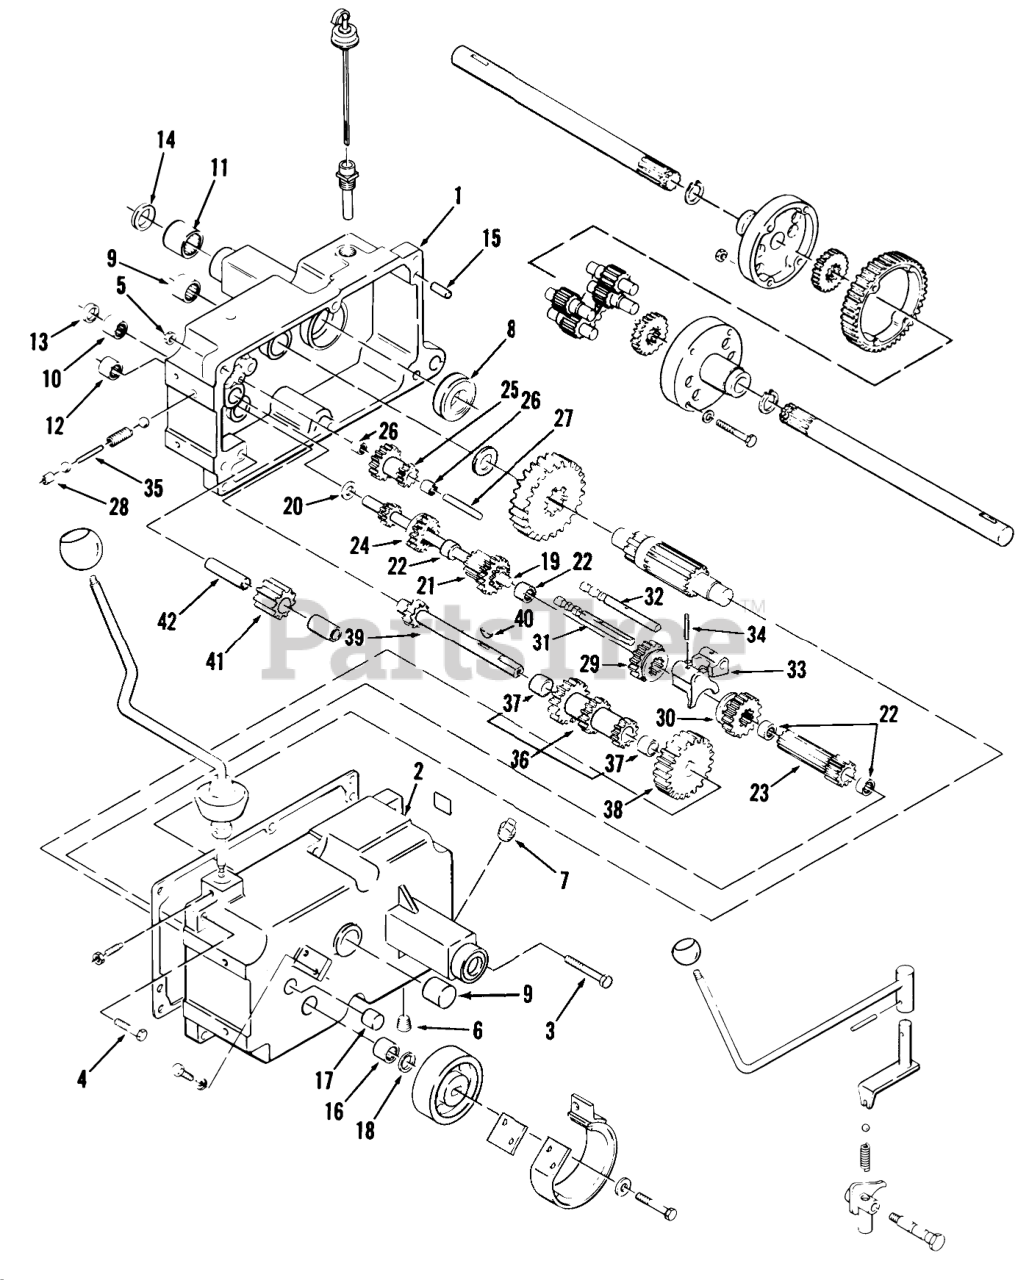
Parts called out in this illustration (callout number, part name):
1	CASE TRANS RH
1	Case-Trans RH 300-Series Only Note: this case half has recess in axle housing for oil seal
1	Case-Trans RH 400-Series Only
1	Case-Trans RH 400-Series Only Note: this case half has recess in axle housing for oil seal
2	CASE TRANS LH
2	Case-Trans LH 300-Series Only Note: this case half has recess in axle housing for oil seal
2	Case Trans LH
2	Case-Trans LH 400-Series Only Note: this case half has recess in axle housing for oil seal
3	Bolt 3/8-16 x 4
4	Bolt
5	NUT
6	PLUG 1/4 PIPE ALLEN
7	Plug
8	BEARING-BALL
9	BEARING-NEEDLE
10	BEARING-NEEDLE
11	BEARING-NEEDLE
11	BEARING
12	BEARING-NEEDLE
13	SEAL-OIL
14	OIL SEAL
14	Seal-Axle 1 ID X 1-1/4 OD 300-series Only
14	SEAL-OIL
15	PIN-DOWEL
16	BEARING-NEEDLE
17	Bearing Needle
18	SEAL-OIL
19	SHAFT-INPUT
20	WASHER-THR
21	GEAR
22	BEARING-NEEDLE
23	GEAR
24	GEAR-SLIDING
25	Gear
26	BEARING-NEEDLE
27	GEAR-SHAFT REDUCTION
28	CUP-PLUG
29	GEAR-HI AND 2ND
30	GEAR-LOW AND REVERSE
31	RAIL-SHIFT
32	RAIL-REAR SHIFT
33	FORK-SHIFT
34	PIN-ROLL
35	PIN-SHIFT
36	GEAR-CLUSTER
37	BUSHING-BRONZE
38	GEAR-CLUSTER SHAFT
39	Cluster Shaft
40	KEY-WOODRUFF
41	GEAR/BUSHING ASM-REVERSE IDLER
42	PIN-DIFFERENTIAL
